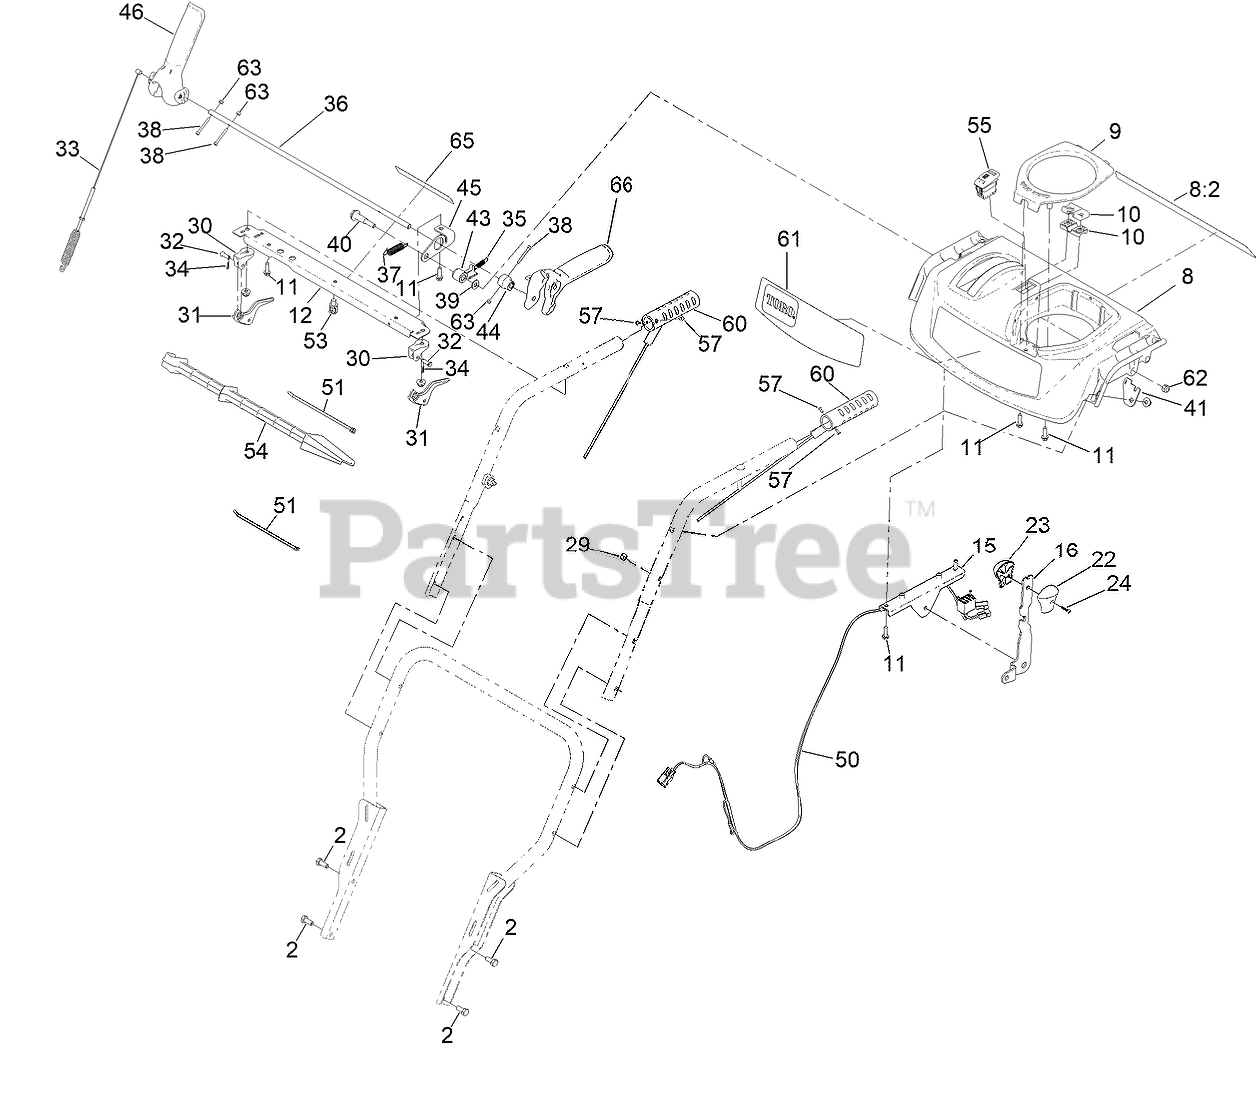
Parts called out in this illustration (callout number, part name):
2	SCREW-HH
8	PANEL-CONTROL, ASSEMBLY
8:2	DECAL-SAFETY
9	COVER-QUICKSTICK
10	SUPPORT-ROD
11	SCREW-PLASTITE, HWH
12	BRACE-CONSOLE
15	BRACKET-SHIFT
16	SELECTOR-SPEED
22	KNOB-SHIFT, LH
23	KNOB-SHIFT, RH
24	SCREW-PPH
29	NUT-HEX
30	MOUNT-LEVER, CLUTCH
31	LEVER-CLUTCH
32	PIN-CLEVIS
33	CABLE-AUGER
34	PIN-HAIR
35	SPRING-LOCKOUT, HANDLE
36	ROD-LOCKOUT
37	SPRING-RETURN, LEVER
38	SCREW-HSH,SPL
39	WASHER-FLAT
40	SCREW-SHOULDER
41	PLATE-SPRING
43	LATCH, LOCKOUT
44	CAM-LOCKOUT
45	LINK-LOCKOUT
46	LEVER-CONTROL
50	HARNESS-WIRE, LED AND HAND WARMERS
51	TIE-CABLE
53	CLIP-TIE
54	STICK-CLEANOUT
55	SWITCH-ROCKER, ON-NONE-OFF (HEATER)
57	RIVET-POP
60	RED HEATED GRIP
61	DECAL-CONSOLE, POWERMAX TRX HD 1432
62	NUT-HEX
63	NUT-LOCK ROHS
65	DECAL-HYDRO
66	LEVER-CONTROL
